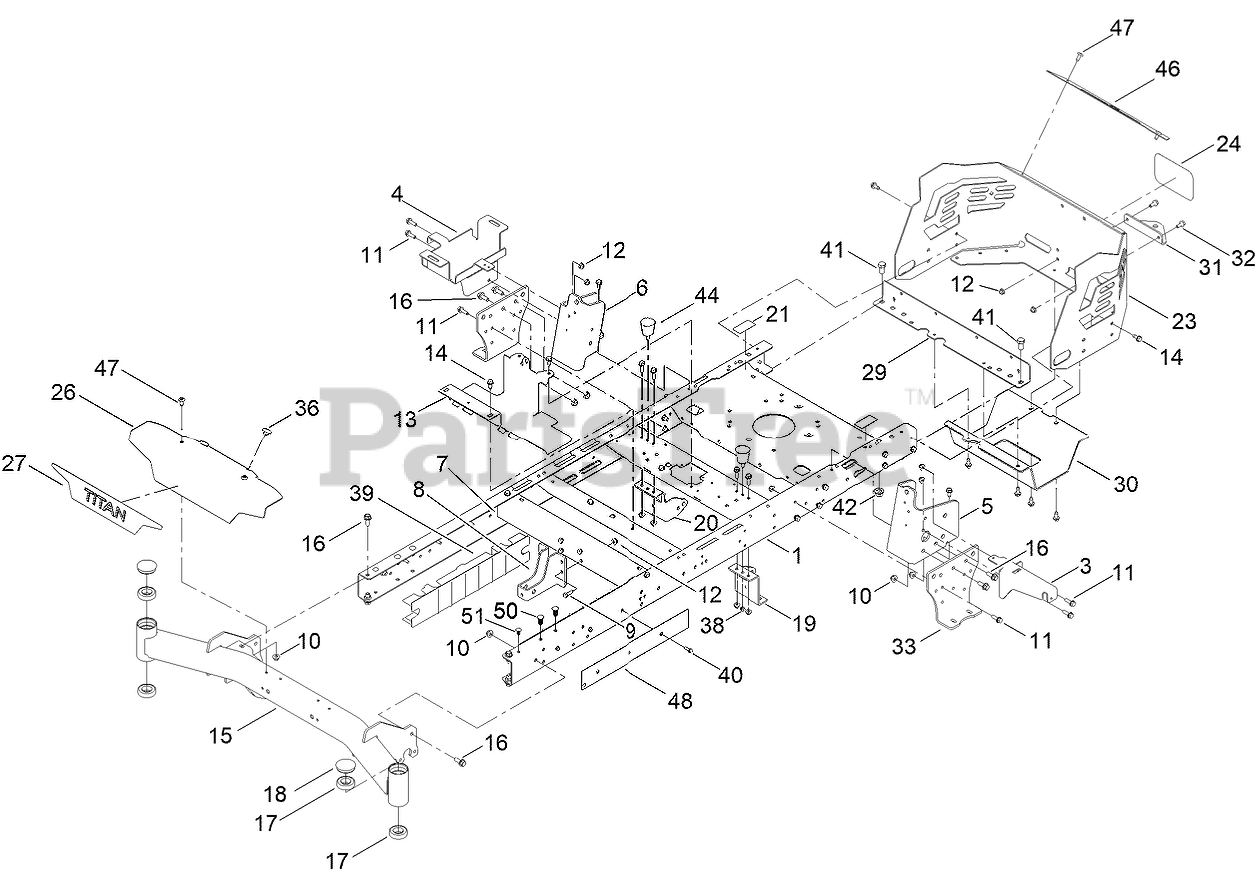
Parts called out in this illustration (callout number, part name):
1	FRAME ASM
3	BRACKET-SUPPORT, POD (LH)
4	TRAY-BATTERY
5	BRACKET-MOUNTING, LH
6	BRACKET-MOUNTING, RH
7	BRACE-CROSS, LOWER
8	BRACKET-MOUNT DAMPER, LOWER
9	SCREW-HH
10	NUT-HF, NI
11	SCREW-HHF
12	NUT-HF
13	BRACKET-MOUNT
14	SCREW-HWHTF
15	FRONT AXLE ASM
16	SCREW-HHF
17	BEARING-BALL
18	CAP-GREASE
19	MOUNT-HYDRO, FRONT (LEFT)
20	MOUNT-HYDRO, FRONT (RIGHT)
21	DECAL-BYPASS
23	GUARD-ENGINE
24	DECAL
26	PLATE-FRONT
27	DECAL-TITAN
29	CROSSMEMBER-REAR, WIDE
30	GUARD-MUFFLER
31	BRACKET-HITCH
32	SCREW-HHF
33	MOUNT-HYDRO
36	BUMPER-SEAT
38	NUT-HEX
39	GUARD-RAIL
40	SCREW-PLASTITE, HWH
41	SCREW-HH
42	NUT-HF
44	BUMPER-RUBBER
46	TRIM-GUARD, ENGINE
48	PLATE-FRAME
50	RIVET-PUSH
51	RIVET-PUSH
